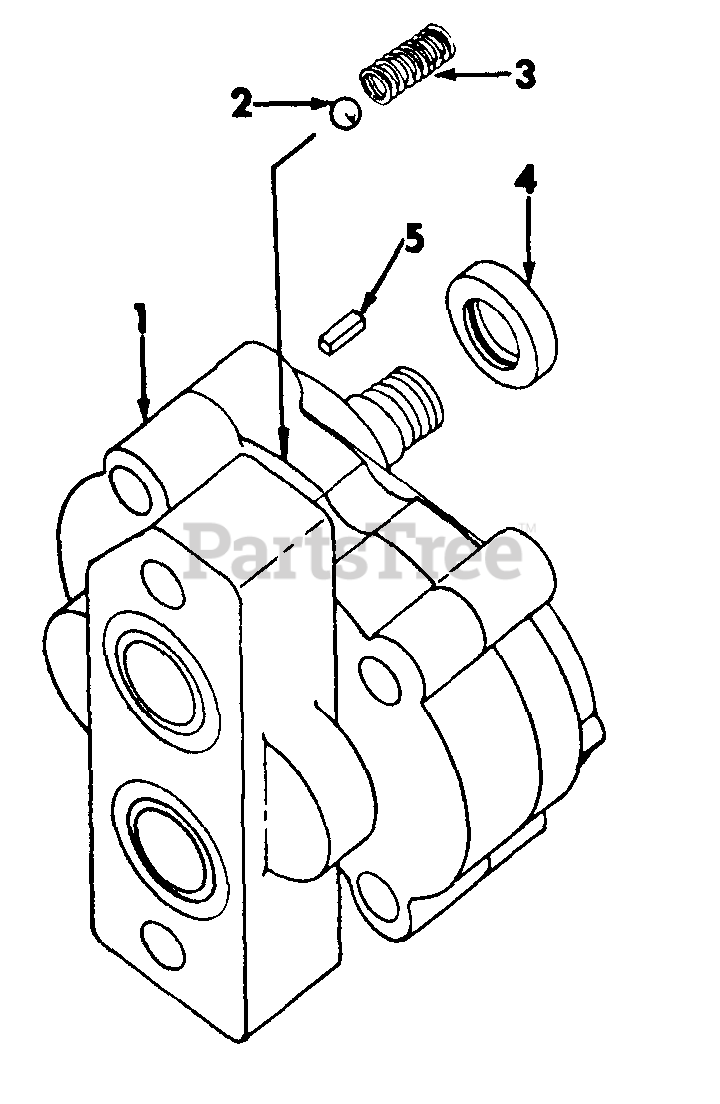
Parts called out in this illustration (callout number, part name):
1	PUMP ASSY, HYDRAULIC CUB 154 LO-BOY TRACTOR WITH S/N 22331 & BELOW
2	NOT USED IN THIS APPLICATION
3	NOT USED IN THIS APPLICATION
4	SEAL, PUMP DRIVE SHAFT OIL
5	KEY, 1/8 X 1/2 WOODRUFF - PUMP DRIVE SHAFT
